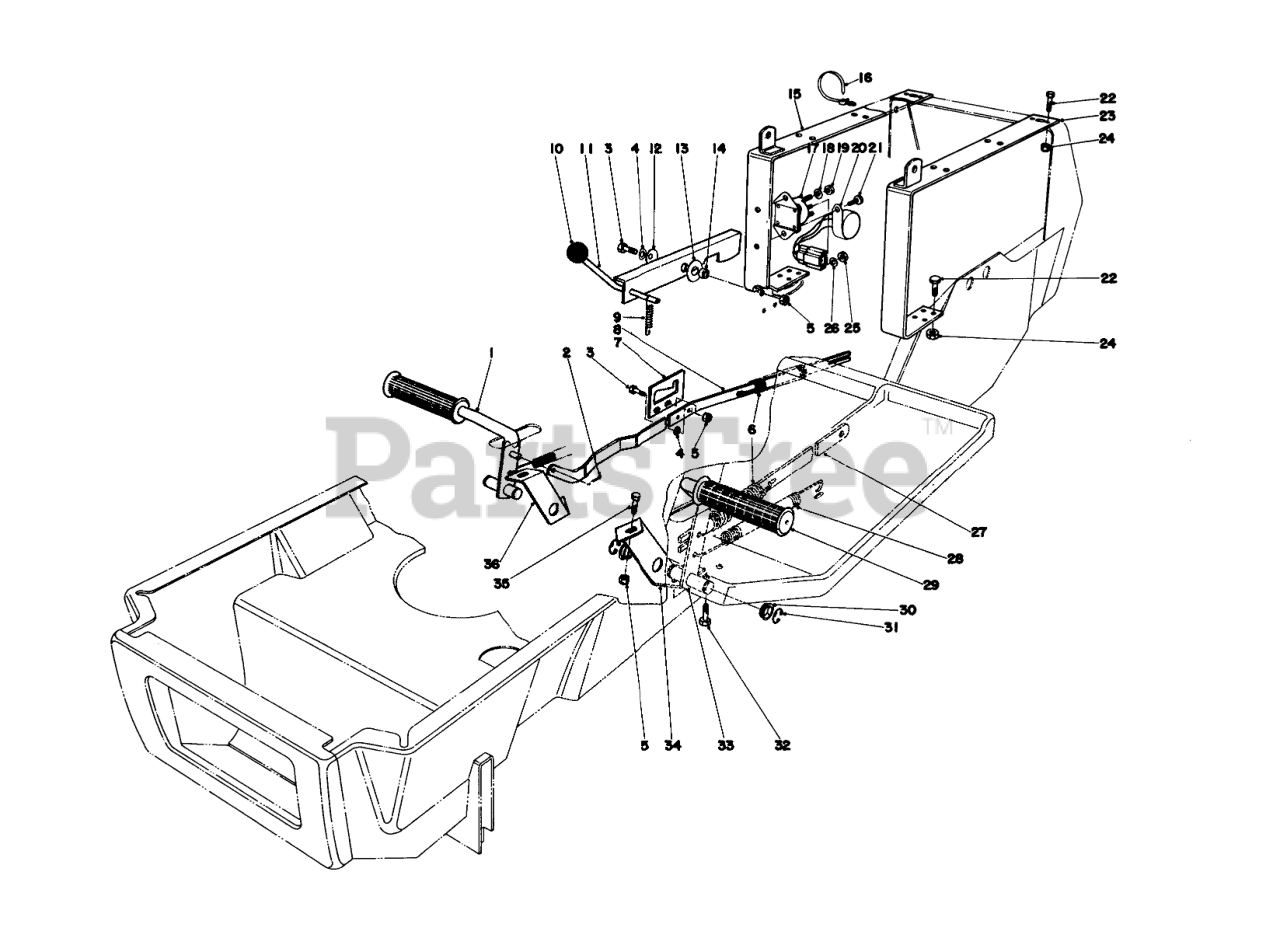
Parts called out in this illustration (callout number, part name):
1	BRAKE PEDAL WA BO
2	PIN-COTTER
3	SCREW-HH
4	WASHER-PLAIN
5	NUT-LOCK, CONE
6	EXT SPRING O
7	LATCH PLT-BRAKE ROD
8	LINK BRAKE ROD WAB
9	CONT ROD SPRING 0
10	Knob
11	PARKING BRAKE WA B
12	Belleville Washer
13	WASHER-PLASTIC
14	SPACER
15	RR BODY STRAP WA B
16	TIE-MOUNT, PUSH
17	Solenoid
18	Lockwasher
19	NUT-JAM, BRASS
20	Module Interlock
21	SCREW-HWH
22	SCREW-HH
23	LH RR BODY STRAP WA B
25	NUT-HEX
26	WASHER-LOCK
27	CLUTCH ROD LINK B
28	SPRING-EXTENSION
29	FOOT PAD
30	Nyliner
31	E-RING
32	SCREW-HWHTF
33	CLUTCH PEDAL WA BO
34	LH PEDAL SUPT B
35	SCREW-HH
36	RH PEDAL SUPT B
